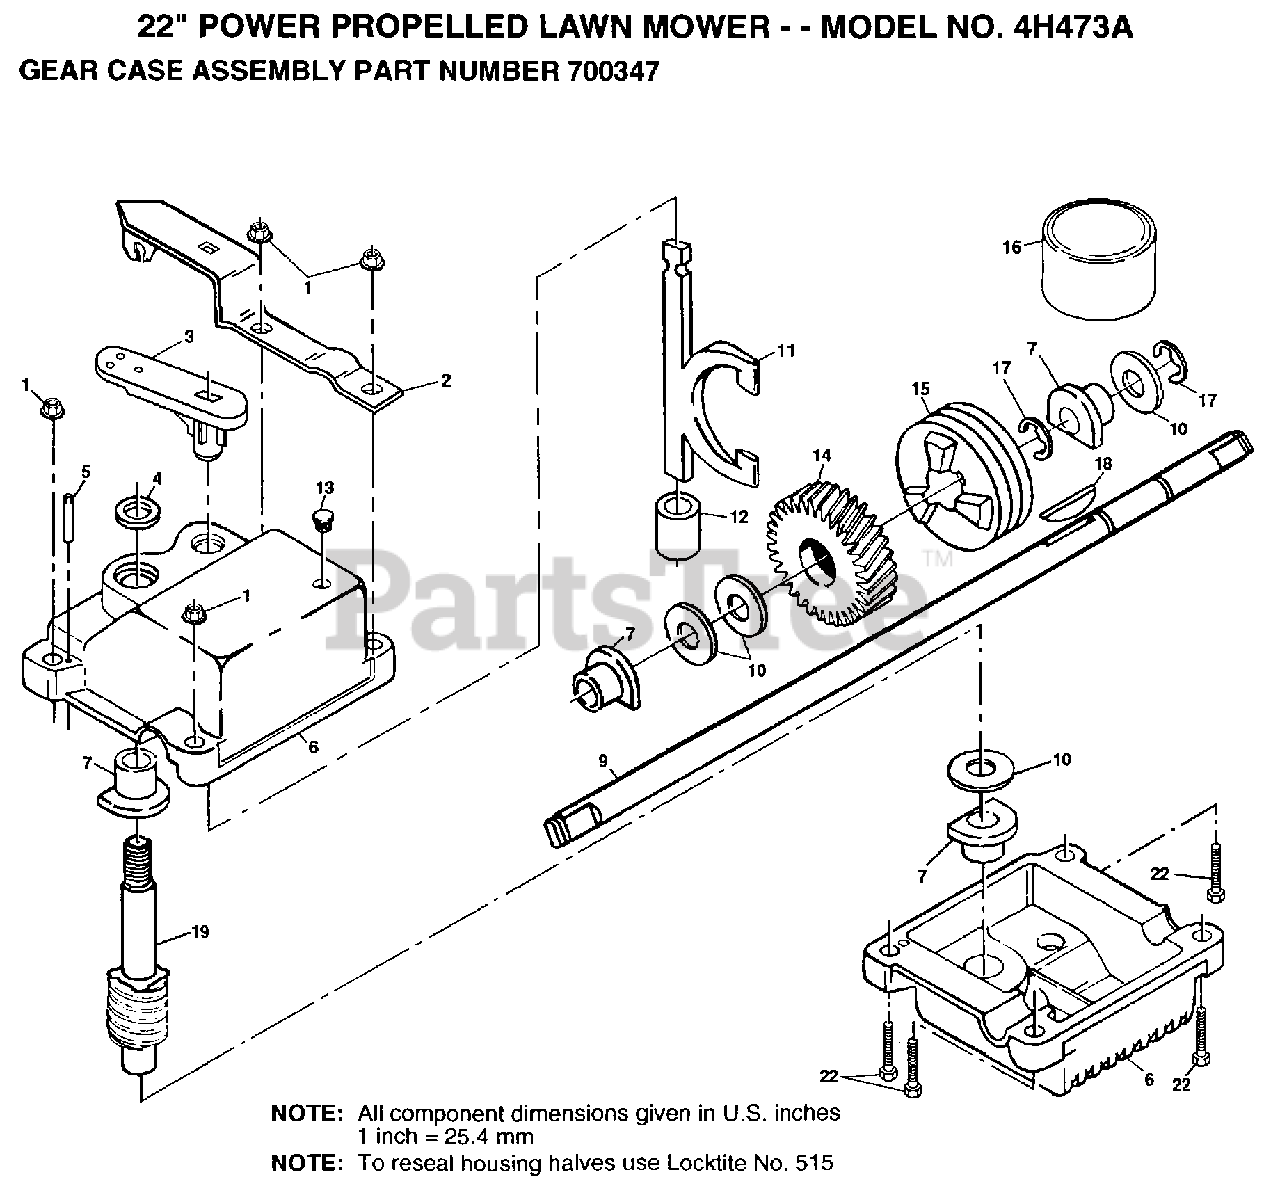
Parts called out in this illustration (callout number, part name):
1	NUT
3	SHIFTER
4	SEAL
5	DRIVE LOK PIN
6	GEARCASE KIT
7	BEARING
9	SHAFT.DRIVE
10	THRUST WASHER
11	CLUTCH YOKE
12	BUSHING.GEAR BOX
13	PLUG PM
14	GEAR.HELICAL
15	CLUTCH JAW
17	RING T
18	HI PRO KEY
19	SHAFT.WORM
22	SCREW.1/4-20
